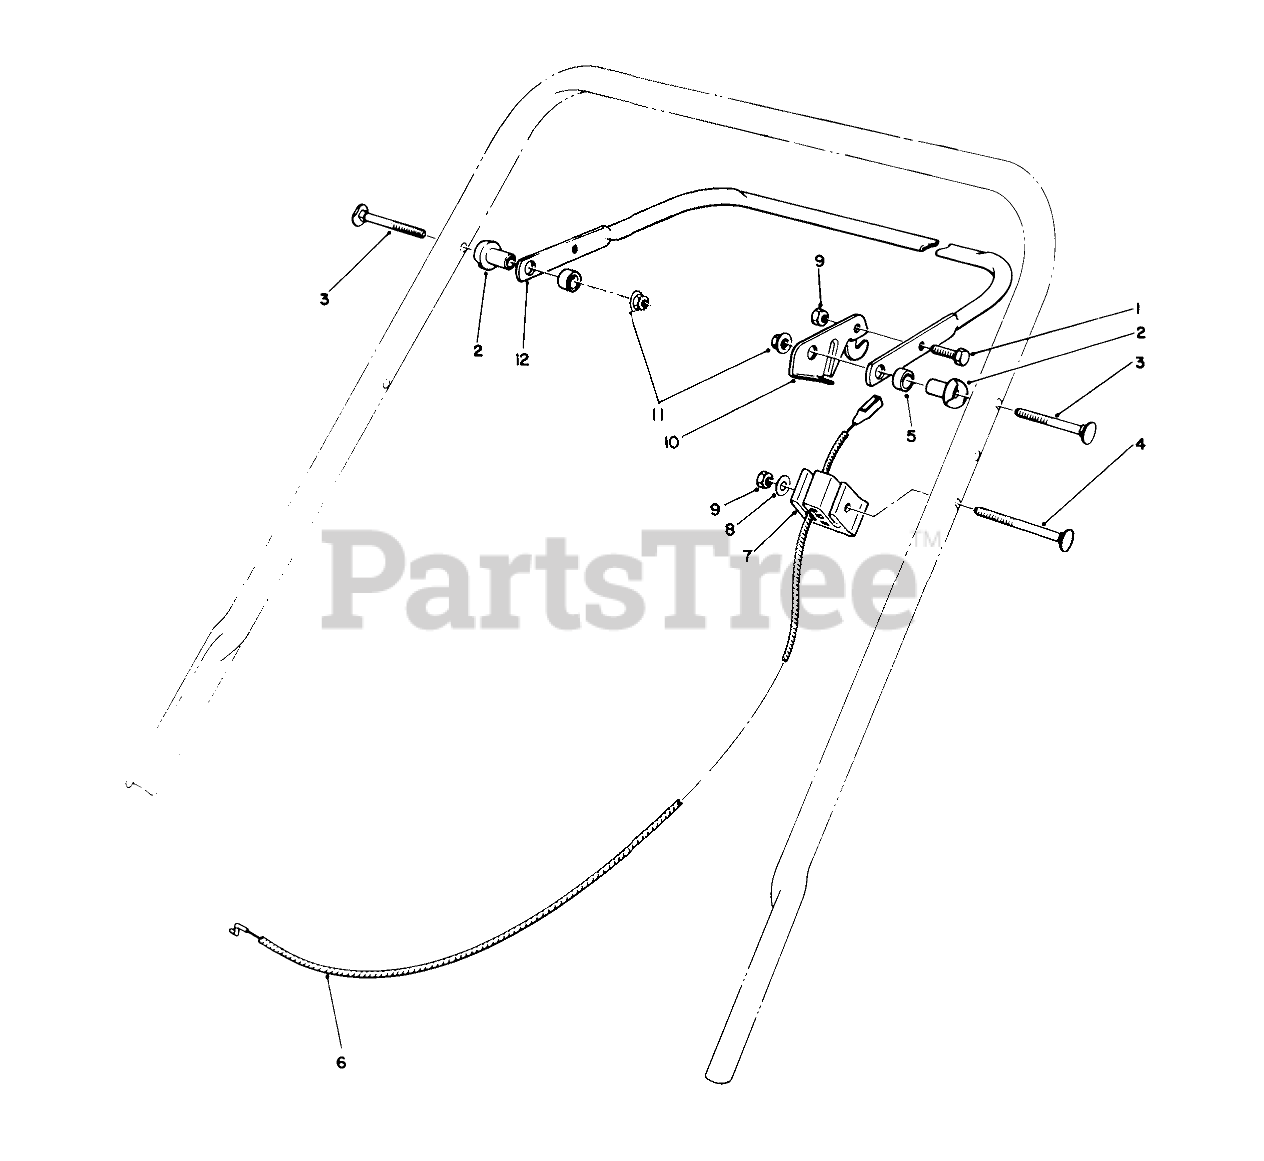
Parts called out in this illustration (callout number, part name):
1	SCREW-HH
2	SPACER-SUPPORT
3	5/16-18 X 2 HNDLE SCREW
4	HANDLE SCREW
5	SPACER-NYLON
6	BRAKE CONTROL
7	SUPPORT-CABLE
8	WASHER-FLAT
9	NUT-LOCK, NI
10	LEVER-CONTROL
11	NUT-LOCK, NI
12	Bar-Control
